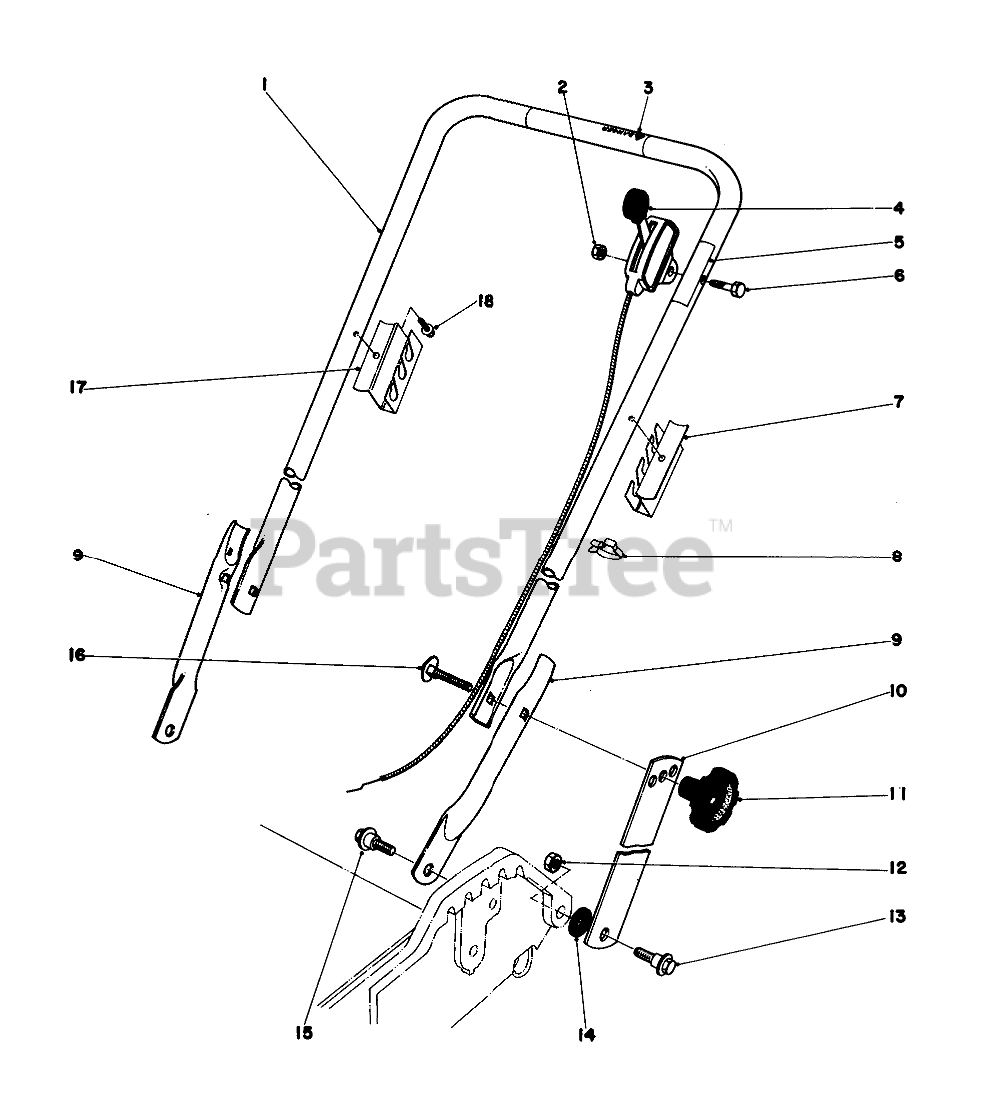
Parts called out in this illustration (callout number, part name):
1	Handle-Upper
2	NUT-LOCK
3	Decal Danger (French & Dutch)
4	Throttle Control
5	Decal Throttle Control
6	SCREW-HH
7	SUPPORT BAG LH
8	BOWDEN CLIP
9	Hand-Lower
10	18" HANDLE LATCH
12	Nut
13	SCREW-SHOULDER
14	SPACER
15	SCREW-SHOULDER
16	SCREW-HANDLE
17	SUPPORT BAG RH
18	SCREW-HWHTF
